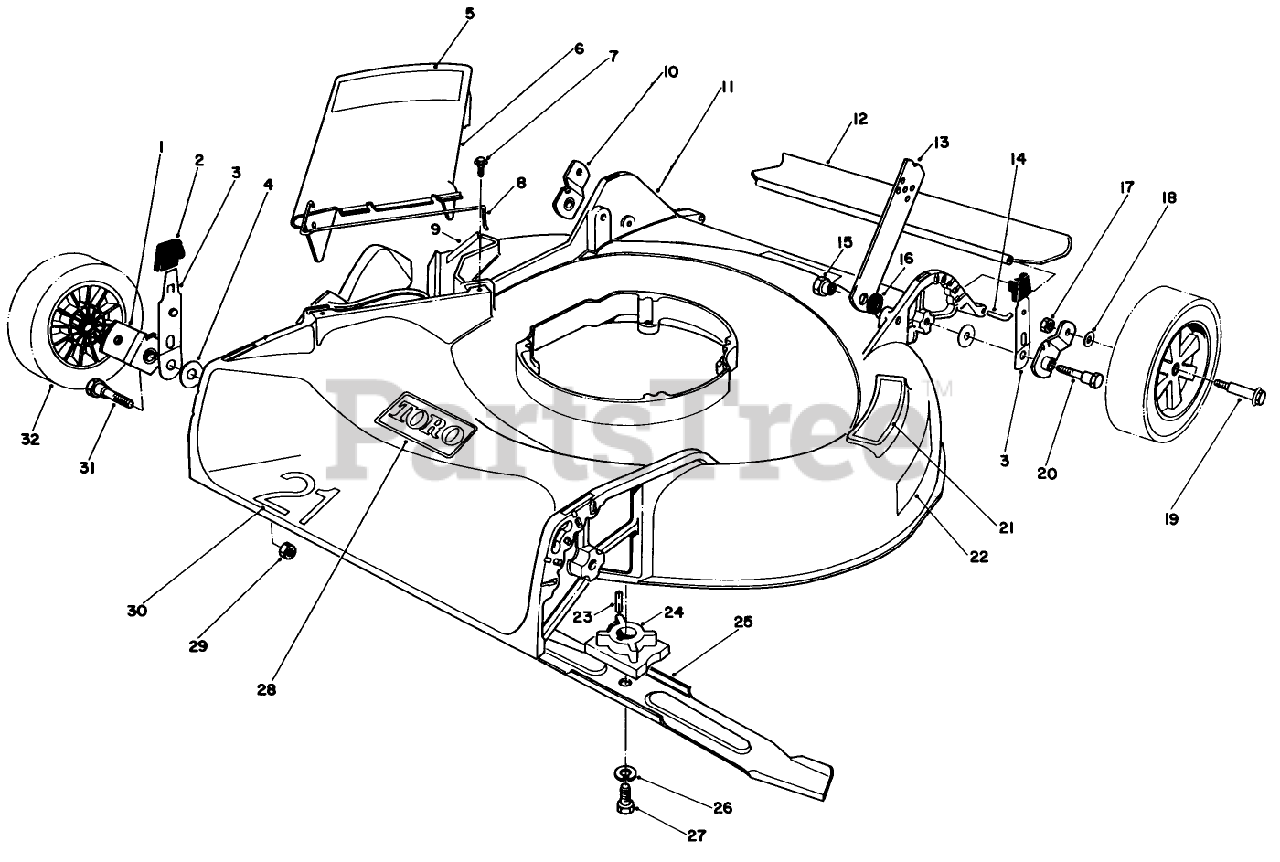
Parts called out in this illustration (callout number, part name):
2	KNOB-ARM
3	SPRING ARM ASM
4	WASHER-PIVOT
7	Screw w/washer
13	HANDLE LATCH
14	SHIELD ROD
15	Pivot Nut
16	Spacer-Handle Latch
18	WASHER
19	Bolt-Wheel
20	PIVOT SCREW
21	STEP PAD DECAL
23	KEY-SQUARE
26	WASHER-LOCK
27	SCREW-HH
29	NUT-LOCK, NI
31	PIVOT SCREW
